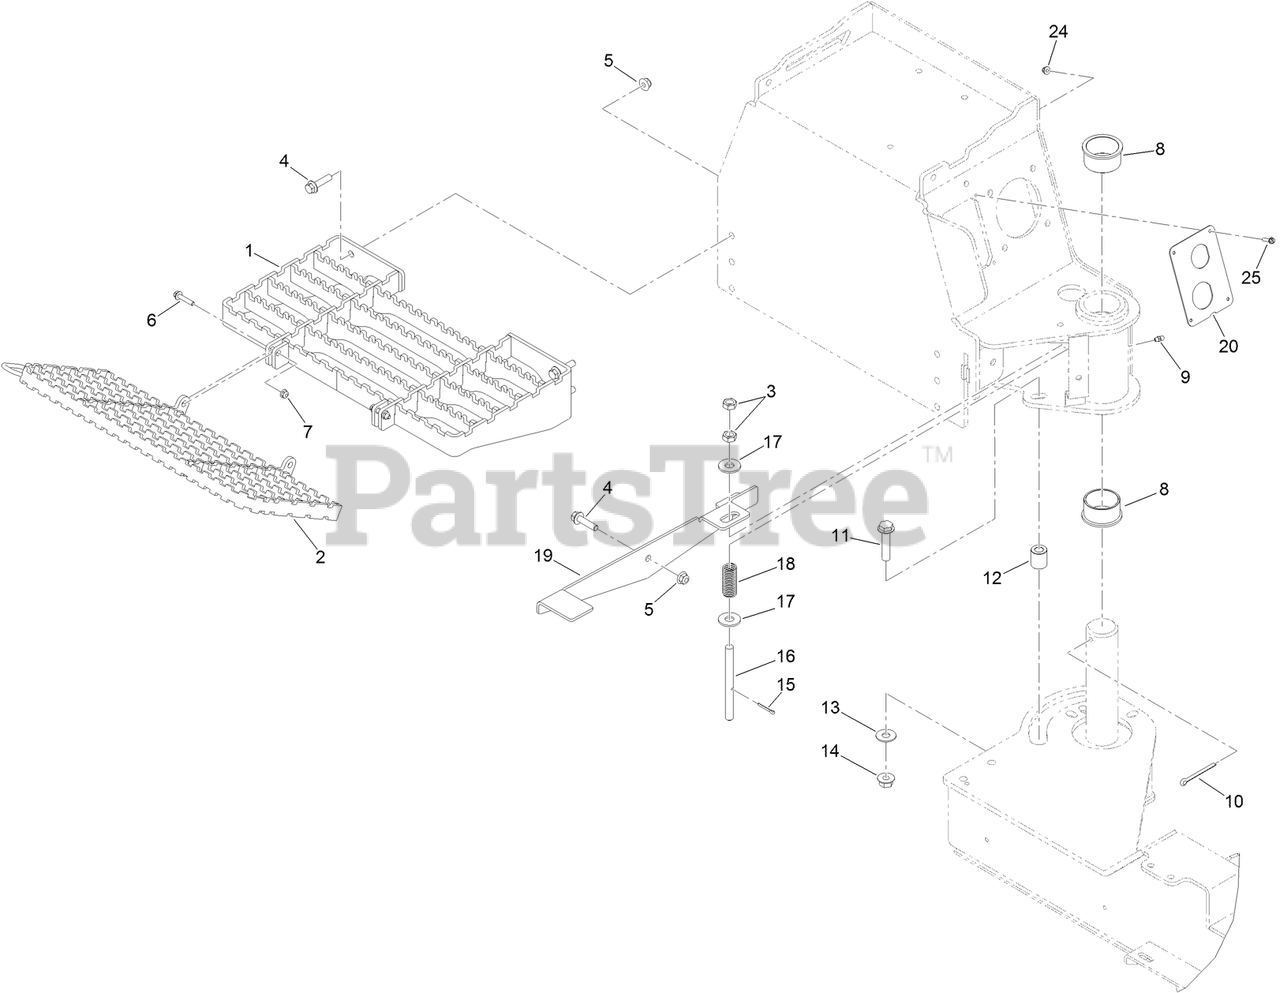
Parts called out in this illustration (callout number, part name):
1	PLATFORM-CONSOLE, LOWER
2	PLATFORM-CONSOLE, UPPER
3	NUT-JAM
4	SCREW-HHF
5	NUT-HF, NI
6	SCREW-HHF
7	NUT-HF
8	BUSHING-FLANGE
9	FITTING-GREASE
10	PIN-COTTER
11	SCREW-HHF
12	SPACER
13	WASHER-FLAT
14	NUT-HHF, WHIZ
15	PIN-COTTER
16	ROD-SWING, SEAT
17	WASHER-FLAT
18	SPRING-PIVOT LOCK, SEAT
19	HANDLE-CONSOLE, SEAT PIVOT
20	PLATE-HARNESS, MOUNT
24	NUT-HF
25	SCREW-HWH
